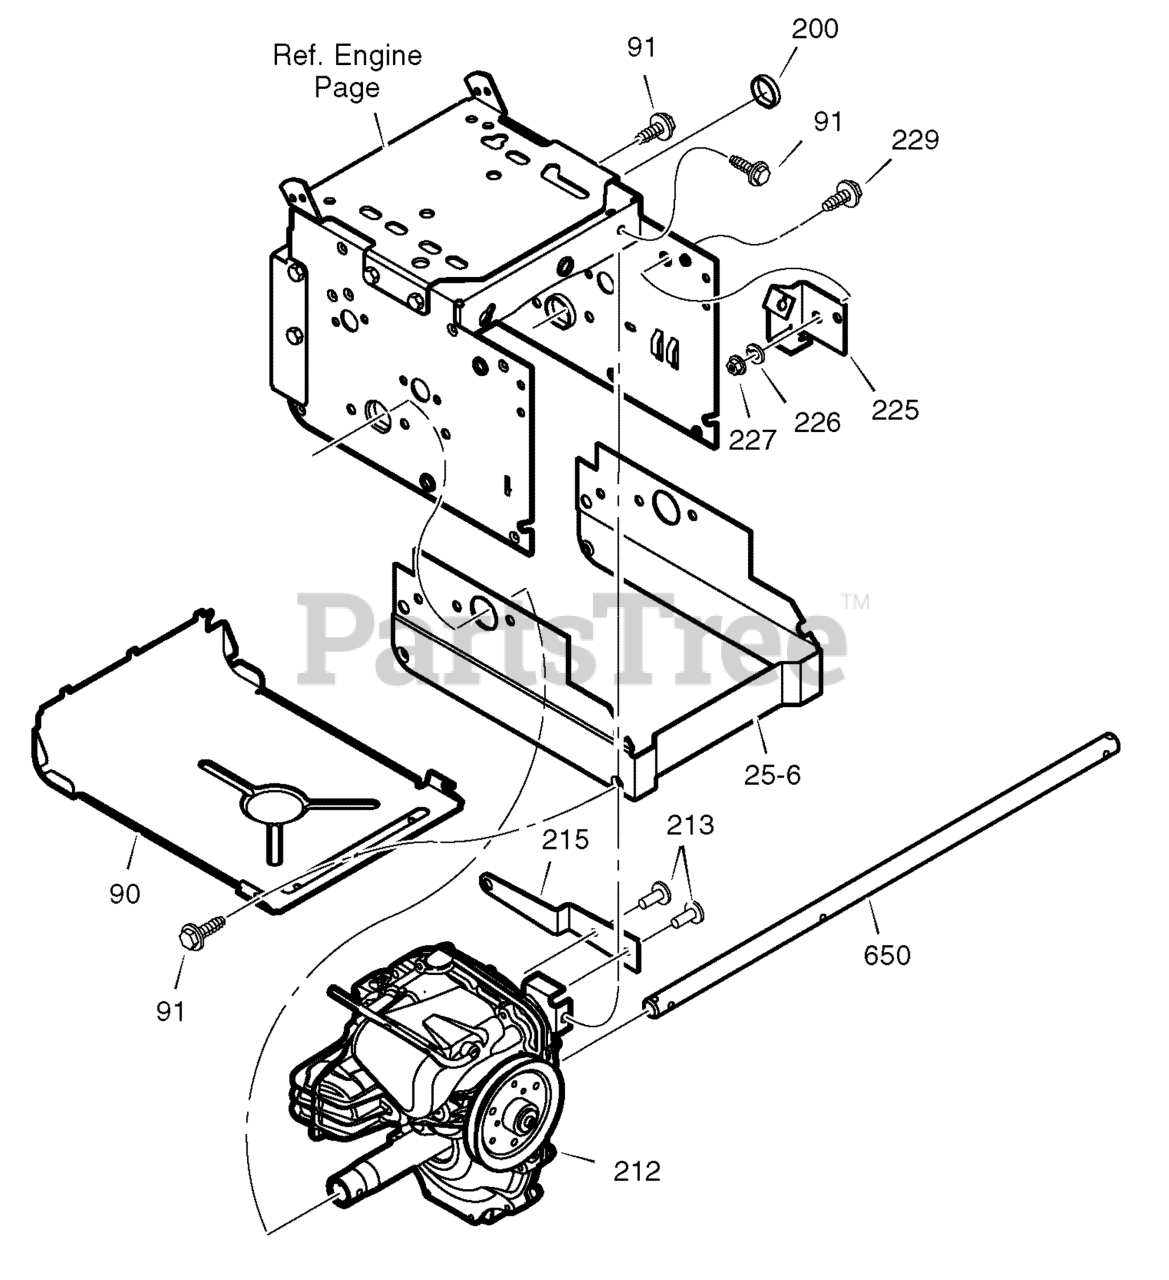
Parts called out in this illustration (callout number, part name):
25-6	FRAME, EXTENSION - HYDRO
90	COVER, BOTTOM
91	SCREW, 1/4-20 X 0.62
200	PLUG, HEYCO
212	TRANSMISSION, HYDRO
213	RIVET, BLIND
215	ARM, CONTROL EXTENSION
225	BRACKET, DRIVE CABLE
226	WASHER, LOCK
227	NUT, HEX JAM - 3/8-16
229	SCREW
650	AXLE, WHEEL
